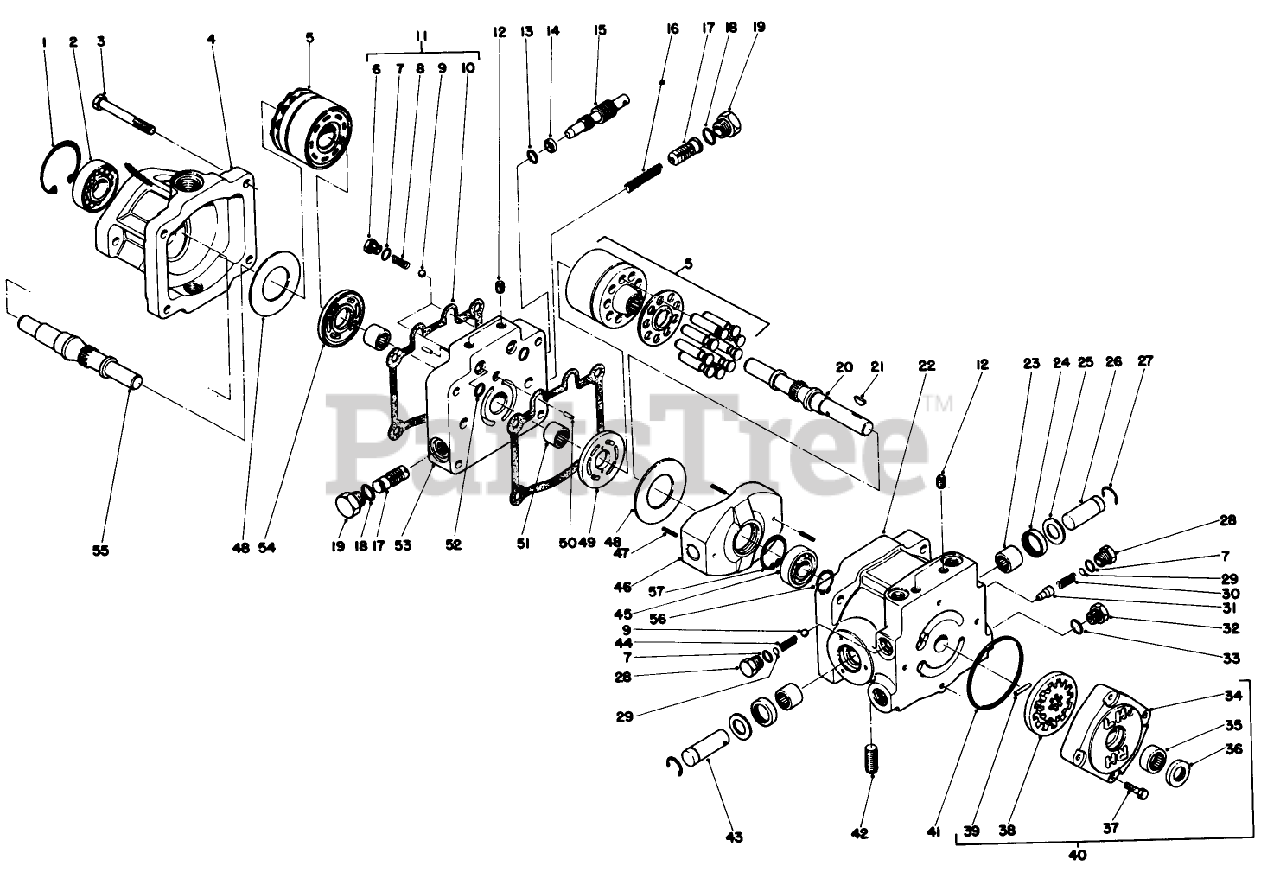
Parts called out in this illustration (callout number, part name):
1	RING-SNAP
2	BEARING
3	SCREW-HH
4	Motor Housing
5	Cylinder Block Kit
6	PLUG-VALVE, CHECK
7	O-RING
8	SPRING-VALVE
10	GASKET
11	Check Valve Kit (Incl. Ref. #6-10)
12	PLUG-PIPE
13	O-RING
14	RING-BACK UP
15	By Pass Valve
16	SPRING-VALVE
17	VALVE ASM
18	O-RING
19	PLUG-HYD, HH
20	Pump Shaft
21	KEY-WOODRUFF
22	PUMP HSG
23	BEARING-NEEDLE
24	SEAL-LIP
25	WASHER-FLAT
26	SHAFT-TRUNNION
27	RING-RETAINING
28	PLUG-HH
29	PACK-SHIM
30	SPRING-VALVE
31	Cone-Relief Valve
32	PLUG-HH
33	O-RING
34	HOUSING-PUMP, CHARGE
35	NEEDLE BRG
36	SEAL-OIL
37	SCREW-HH
38	Gerotor ASM
39	PIN-STRAIGHT, HEADLESS
40	Charge Pump (Incl. Ref. #34-39)
41	O-RING
42	UNION-FILTER
43	SHAFT-TRUNNION
44	SPRING-VALVE
45	BEARING-BALL
46	PLATE-SWASH, VARIABLE
47	PIN-SPRING
48	PLATE-THRUST
49	PLATE-VALVE, PUMP
50	PIN-DOWEL
51	BEARING-NEEDLE
52	O-RING
53	Center Section
54	PLATE-VALVE, MOTOR
55	Motor Shaft
56	RING-SNAP, EXT
57	RING-RETAINING
